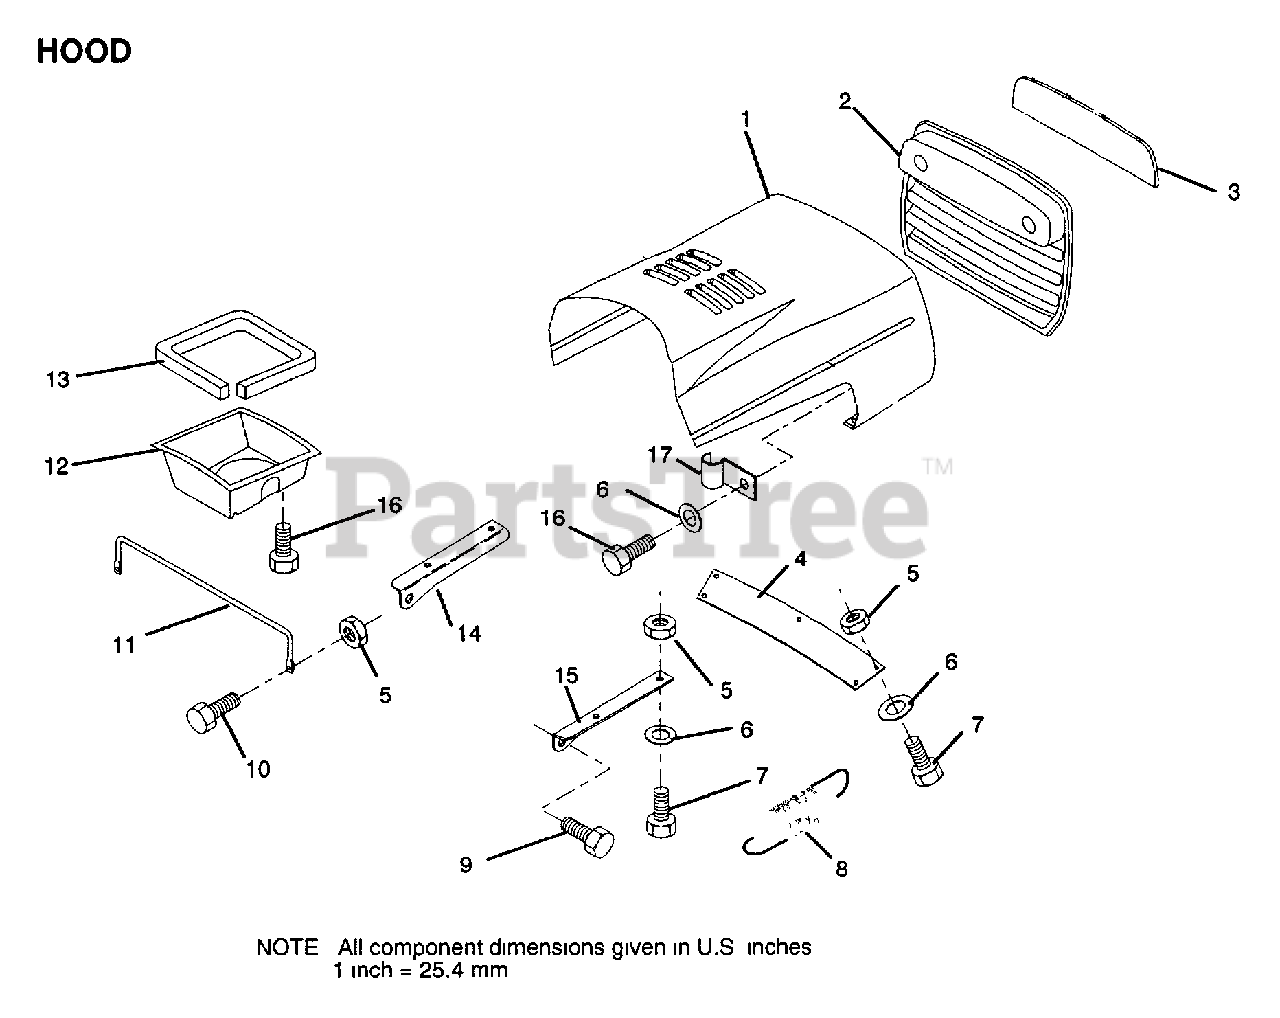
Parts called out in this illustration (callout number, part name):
2	No Desciption for Part
4	STRAP,GRILL T
5	NUT
6	WASHER
7	BOLT
8	EXT SPRING
11	"BRACE,HOOD"
12	"DUCT,AIR"
13	FOAM STRIP LT
14	BRKT HOOD LH
15	BRKT HOOD RH
17	CLIP T
